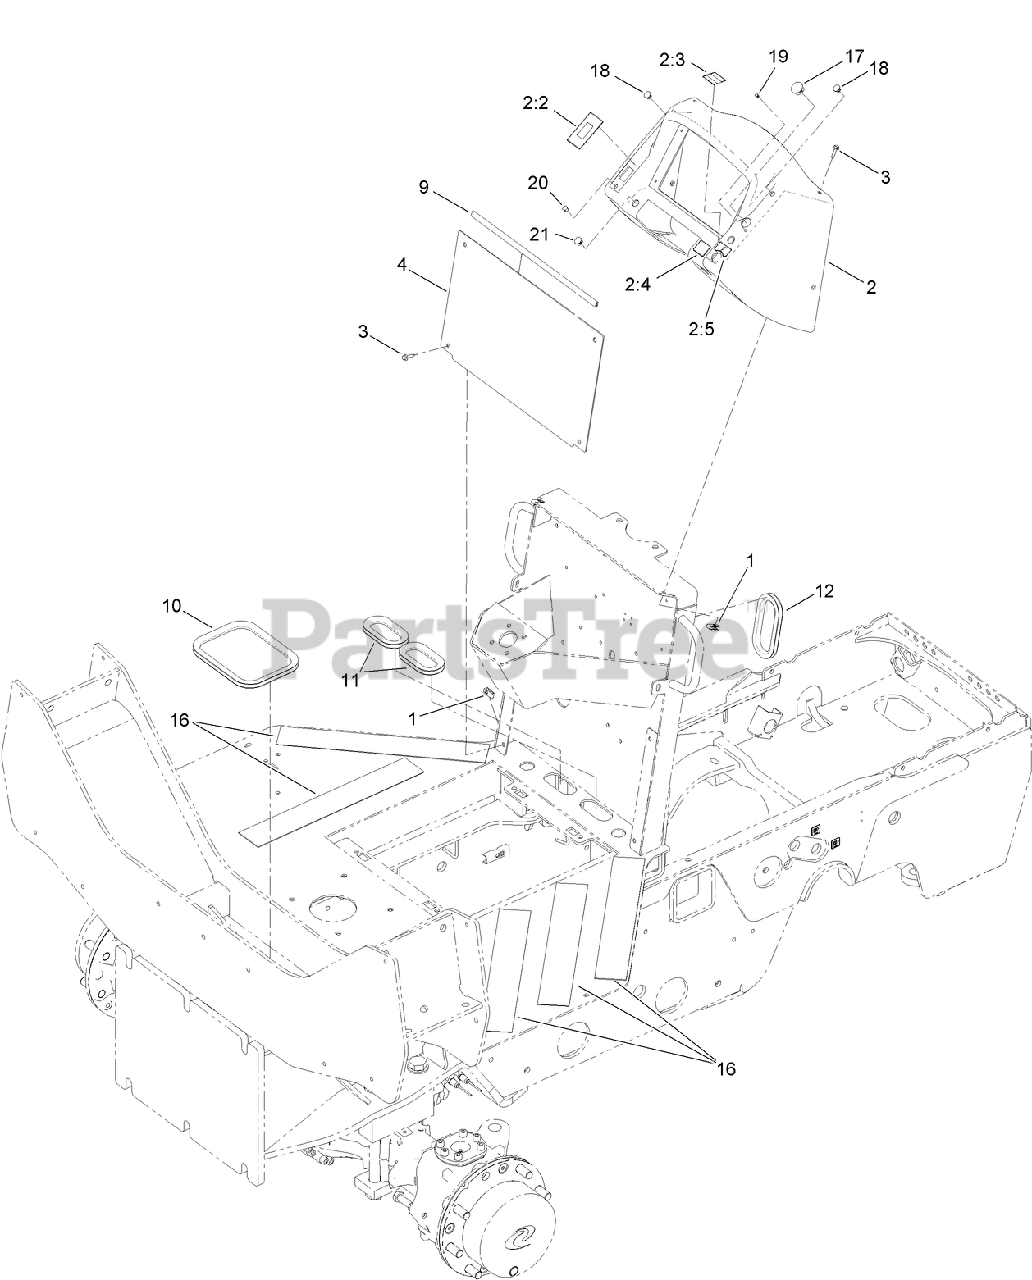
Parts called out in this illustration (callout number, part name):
2	DASH PANEL ASM
2:2	DECAL-P BRAKE
2:3	DECAL-THROTTLE
2:4	DECAL-IGNITION
2:5	DECAL-AUX POWER
3	SCREW-HHF
4	PLATE-KICK
9	TRIM-EDGE
10	TRIM-EDGE
11	TRIM-EDGE
12	TRIM-EDGE
16	TAPE-ANTI SKID, LOWER STEP
17	PLUG-DOME
18	PLUG-HOLE
19	PLUG-HOLE
20	Plug-Dome
21	PLUG-DOME
